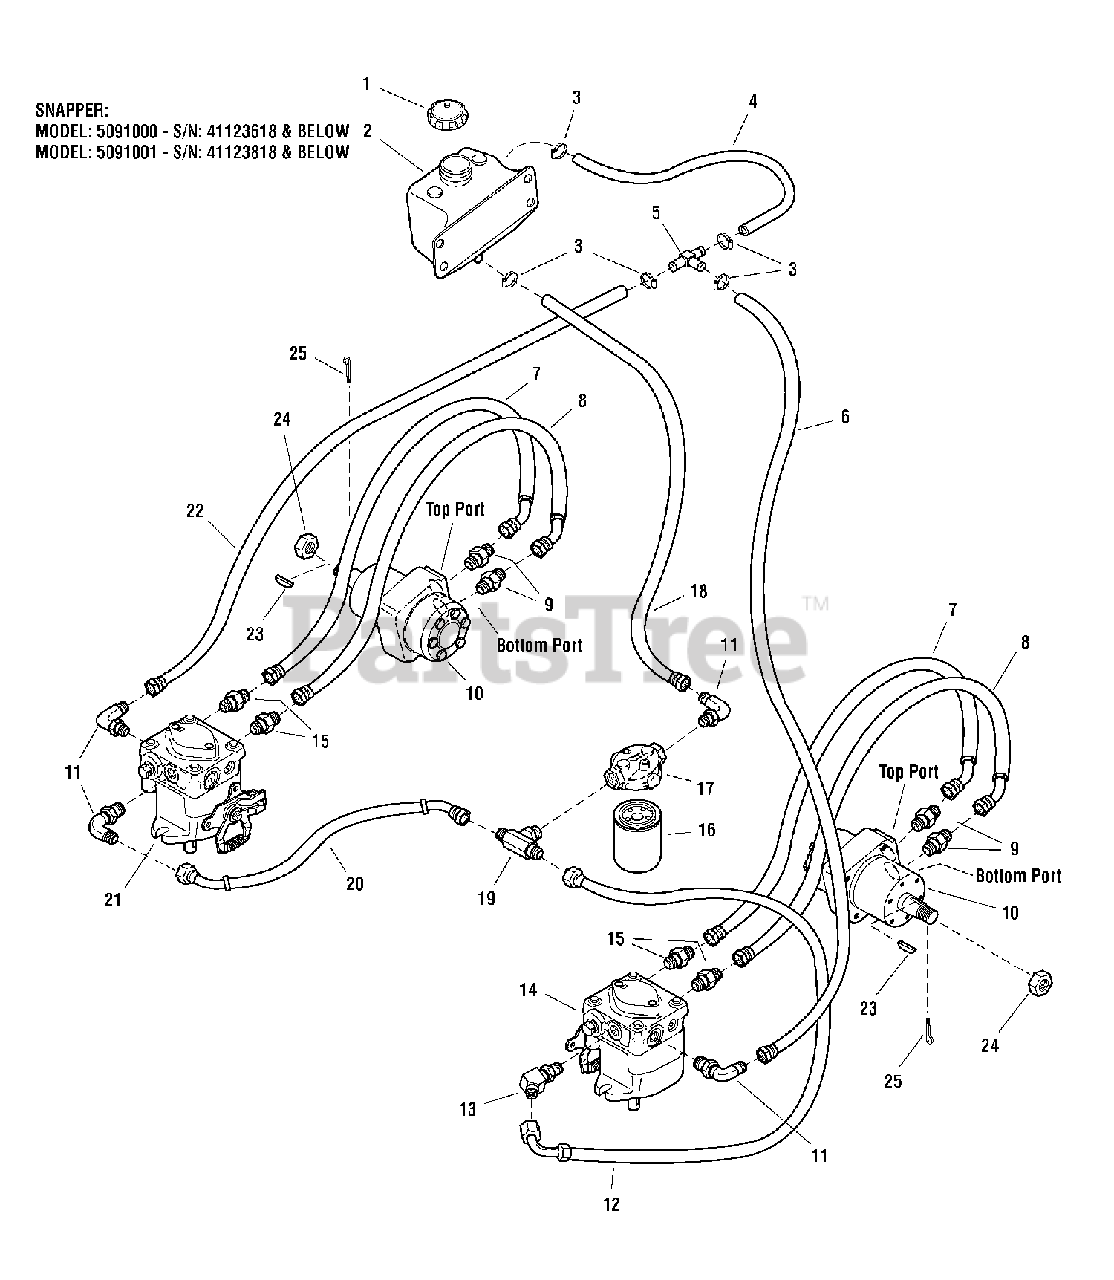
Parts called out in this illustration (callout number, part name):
1	CAP
2	HYDRAULIC TANK
3	CLAMP, #6 HOSE
4	HOSE, 3/8 X 8-1/2" LONG
5	TEE FITTING
6	HOSE ASSEMBLY, 26" LONG
7	HOSE ASSEMBLY, HI PRESS, 25-1/2"
8	HOSE ASSEMBLY, HI PRESS, 29"
9	FITTING, ADAPTER
10	WHEEL MOTOR
11	FITTING, 90 DEG. O-RING
12	HOSE ASSEMBLY, 16-1/2" LONG
13	FITTING, 45 DEG. 0-RING
14	HYDRAULIC PUMP, LH (PG1HQQ DW1X-XXXX)
15	FITTING, ADAPTER
16	FILTER
17	FILTER HEAD
18	HOSE ASSEMBLY, 11-3/4" LONG
19	FITTING, TEE
20	HOSE ASSEMBLY, 4-1/2" LONG
21	HYDRAULIC PUMP, RH (PG1KQQ DW1X-XXXX)
22	HOSE ASSEMBLY, 6" LONG
23	KEY
24	NUT, CASTLE
25	PIN, COTTER, 1/8 X 1-1/4
